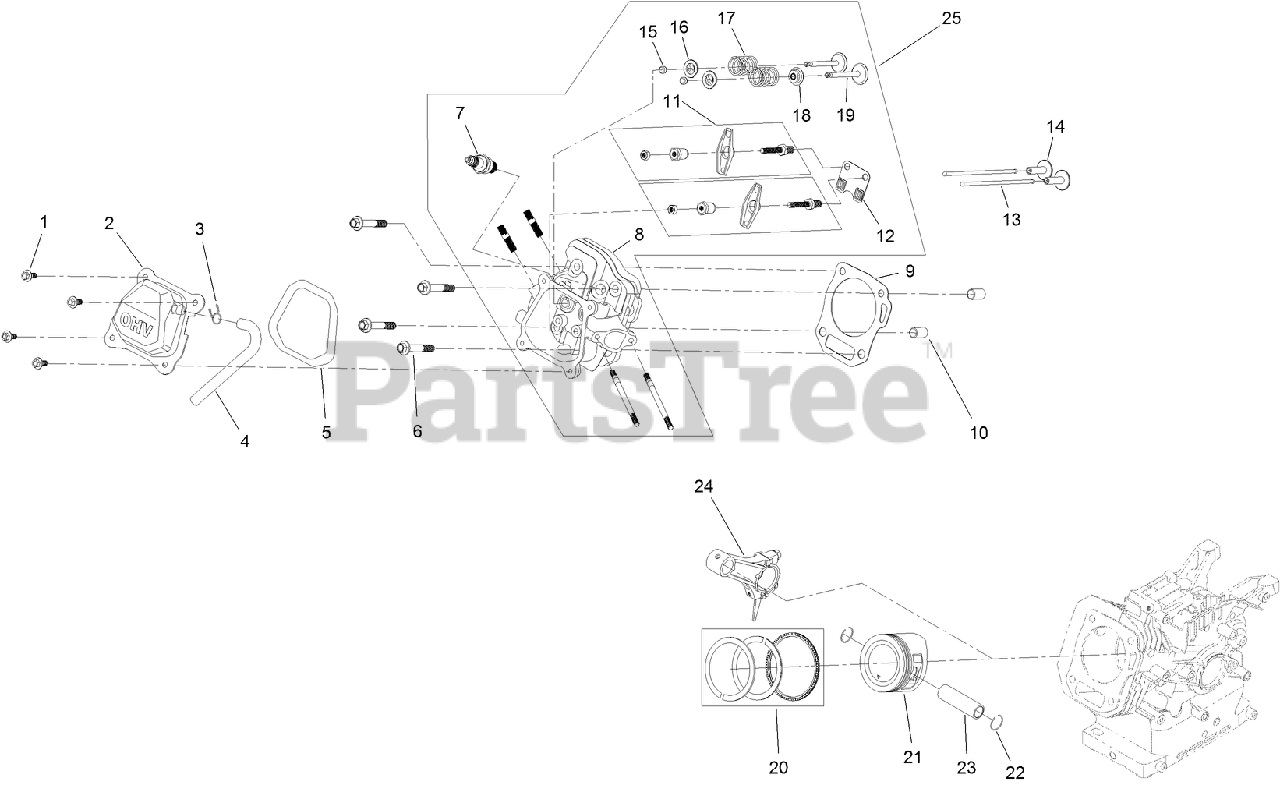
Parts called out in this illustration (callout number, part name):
1	SCREW-HHF
2	COVER-VALVE
3	CLAMP-HOSE
4	TUBE-BREATHER
5	GASKET-COVER, VALVE
6	SCREW-HHF
7	SPARK PLUG
8	HEAD-CYLINDER
9	GASKET-HEAD, CYLINDER
10	PIN-DOWEL
11	ROCKER ARM ASM
12	PLATE-GUIDE, PUSH ROD
13	ROD-PUSH
14	TAPPET-VALVE
15	ROTATOR-VALVE
16	RETAINER-SPRING, VALVE
17	SPRING-VALVE
18	SEAL-STEM, VALVE
19	VALVE SET
20	RING SET, PISTON
21	PISTON
22	CLIP-PIN, PISTON
23	PIN-PISTON
24	CONNECTING ROD ASM
25	COMPLETE HEAD ASM
